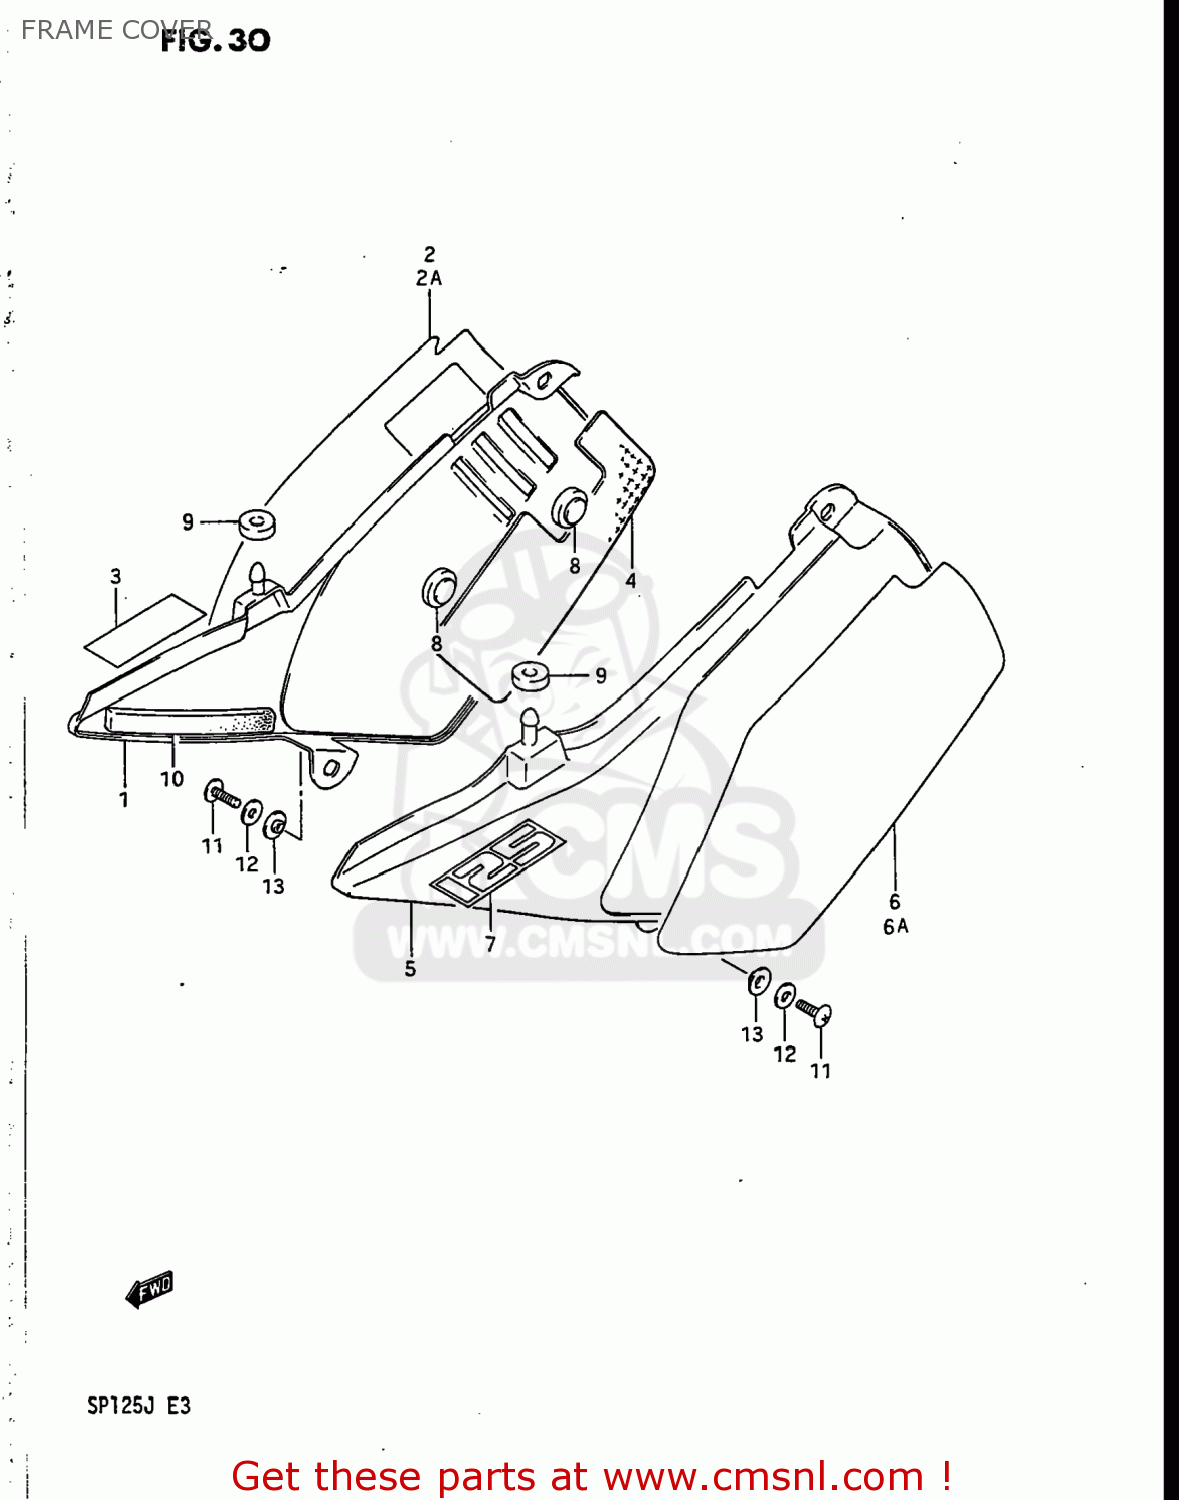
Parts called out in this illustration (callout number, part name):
1	COVER,FRAME,RIGHT
2	TAPE SET,FRAME COVER
2A	TAPE,FRAME COVER,RIGHT (WHITE)
3	EMBLEM
4	SHIELD,FRAME COVER,RIGHT
5	COVER,FRAME,LEFT
6	TAPE SET,FRAME COVER
6A	TAPE,FRAME COVER,LEFT (WHITE)
7	EMBLEM
8	CUSHION
9	CUSHION,SIDE COVER BOSS
10	CUSHION,FRAME COVER
11	SCREW
12	WASHER (6.5X18X1.6)
13	WASHER
